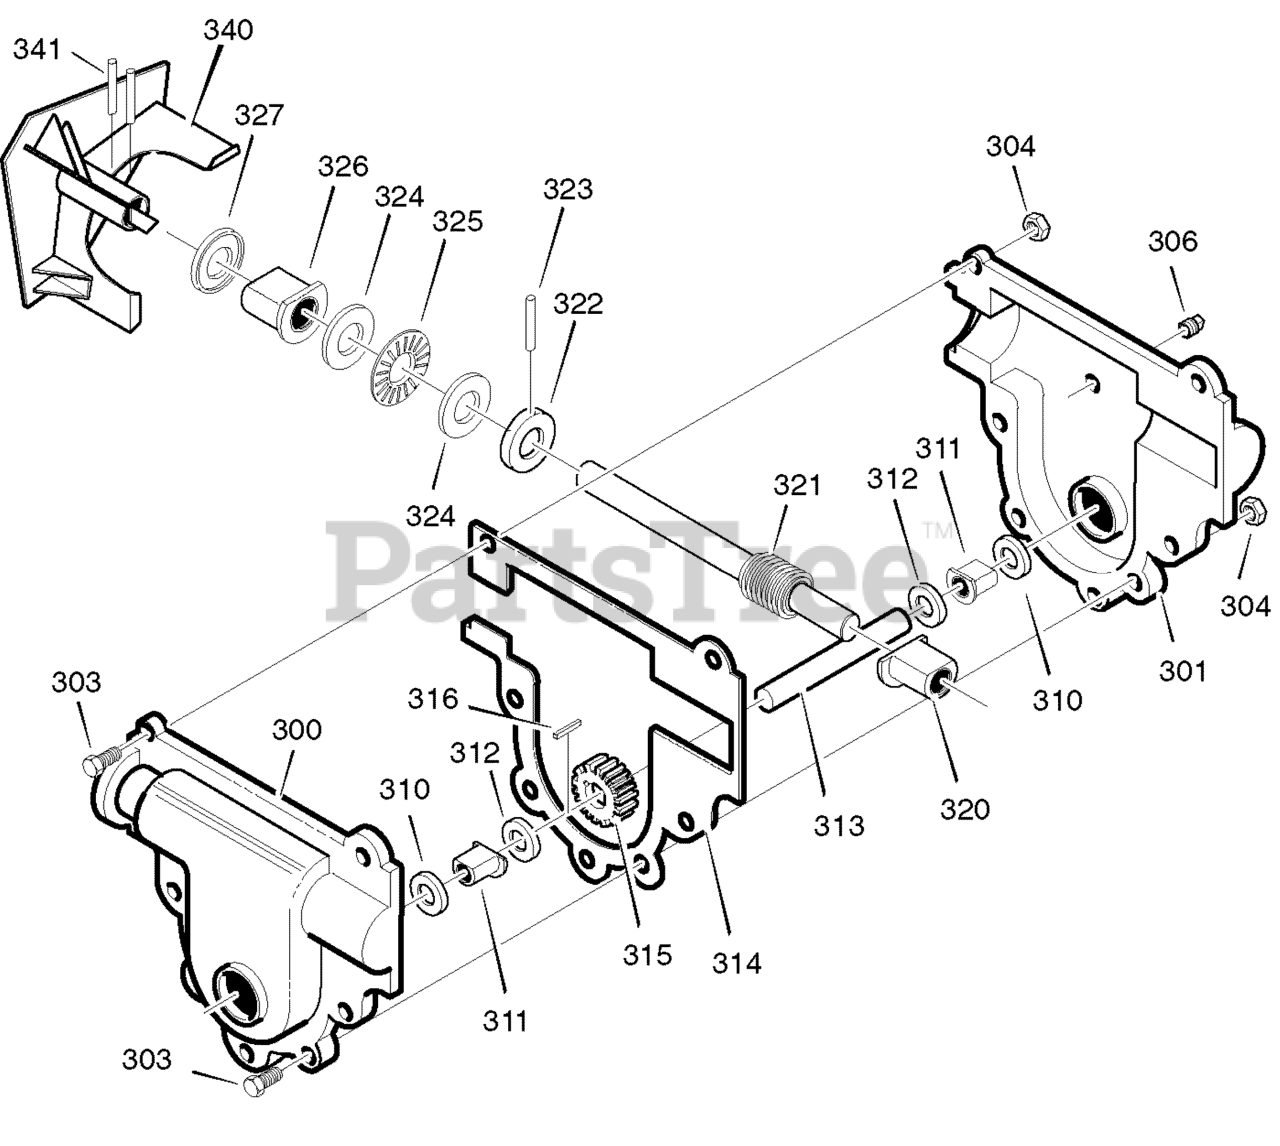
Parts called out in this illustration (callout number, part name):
300	CASE, GEAR, RH
301	CASE, GEAR, LH
304	NUT
306	SCREW
310	SEAL, OIL
311	BEARING, FL
312	WASHER, FLAT
313	SHAFT, OUTPUT
314	GASKET
315	GEAR, WORM
316	KEY, WOODRUFF
320	BRNG, FL
321	SHAFT, INPUT
322	COLLAR, THRUST
323	PIN, SPRING
324	WASHER, FLAT
325	BRNG, ROLL
326	BRNG, FL
327	SEAL, OIL
340	IMPELLER
341	PIN, SPRING
